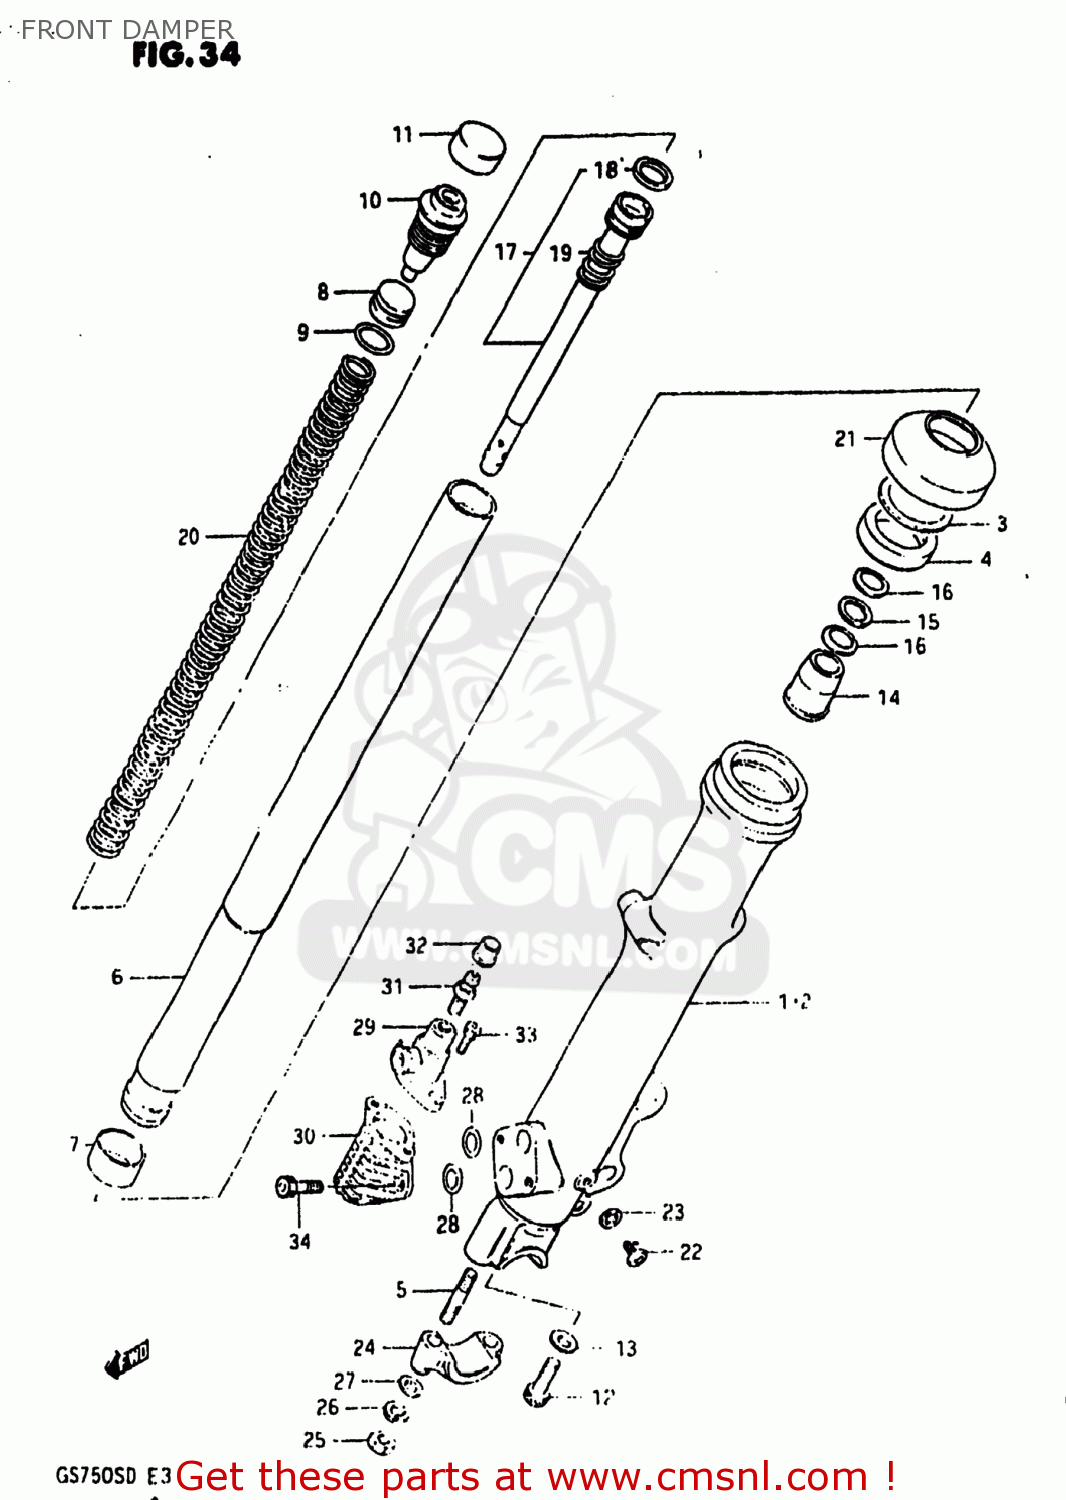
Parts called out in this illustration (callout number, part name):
0	DAMPER ASSEMBLY,LEFT
1	TUBE,FORK,OUTER,RIGHT
2	TUBE,OUTER,LEFT
3	RING,STOPPER
4	OIL SEAL,FRONT FORK
5	STUD 8X30
6	TUBE,INNER
7	PISTON
8	PISTON,FREE
9	O-RING
10	CAP
11	CAP,RUBBER
12	BOLT,FORK CYLINDER(10X25)
13	GASKET (NAS)
14	PIECE,OIL LOCK
15	WASHER
16	SPRING,LEAF
17	CYLINDER,FRONT FORK
18	RING,PISTON
19	SPRING,REBOUND
20	SPRING,FRONT FORK
21	SEAL,DUST
22	SCREW
23	GASKET,DRAIN,PLUG (NAS)
24	HOLDER,AXLE
25	NUT
26	LOCK WASHER
27	WASHER
28	O RING
29	PLANGER SET,MODULATOR
30	VALVE SET,MODULATOR
31	BREATHER,AIR
32	CAP,BREADER
33	BOLT, MODULATOR (5X12)
34	BOLT,FRONT FORK
